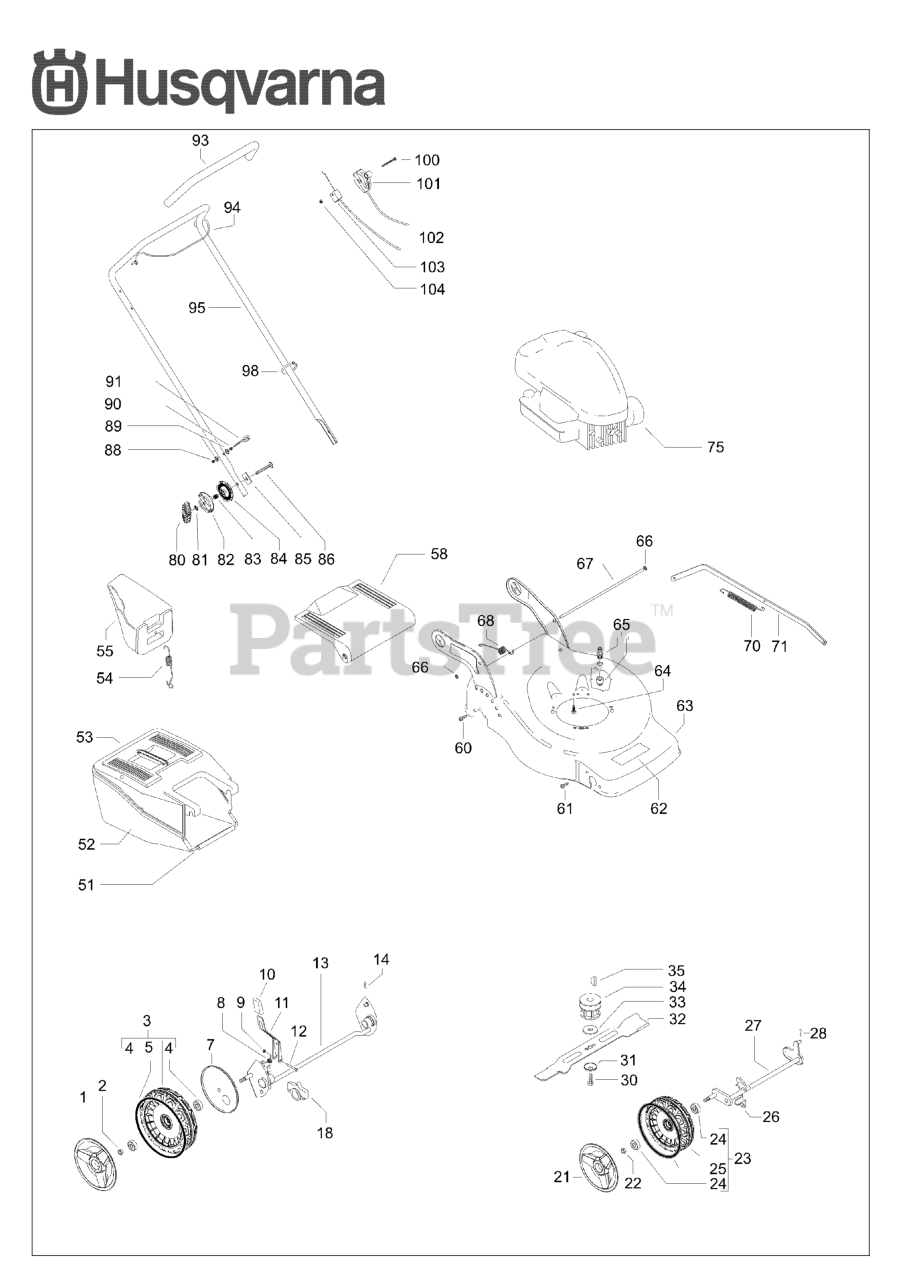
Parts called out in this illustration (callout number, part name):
11	LIFTING LEVER ASSY FOR REAR AX
32	MOWER BLADE COMBI
102	BRAKE WIRE
